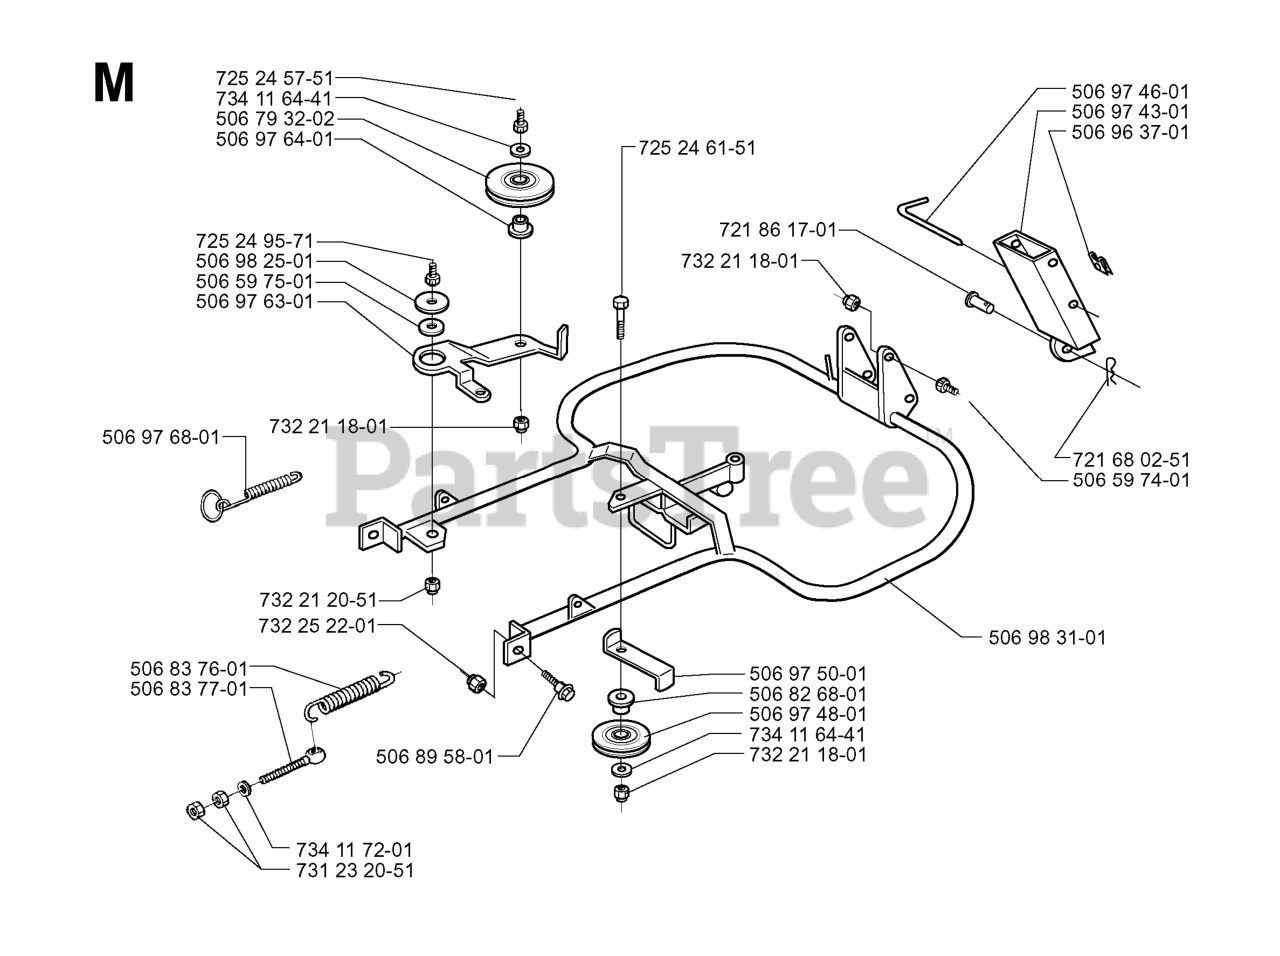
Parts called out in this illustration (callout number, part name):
10	KIT GASKET 28CC
55	CRANKCASE CAST LE28
57	KIT CRANKSHAFT ASSY
57	ASSY CRANKSHAFT FORGED ROD
60	KIT PISTON & CYLINDER
